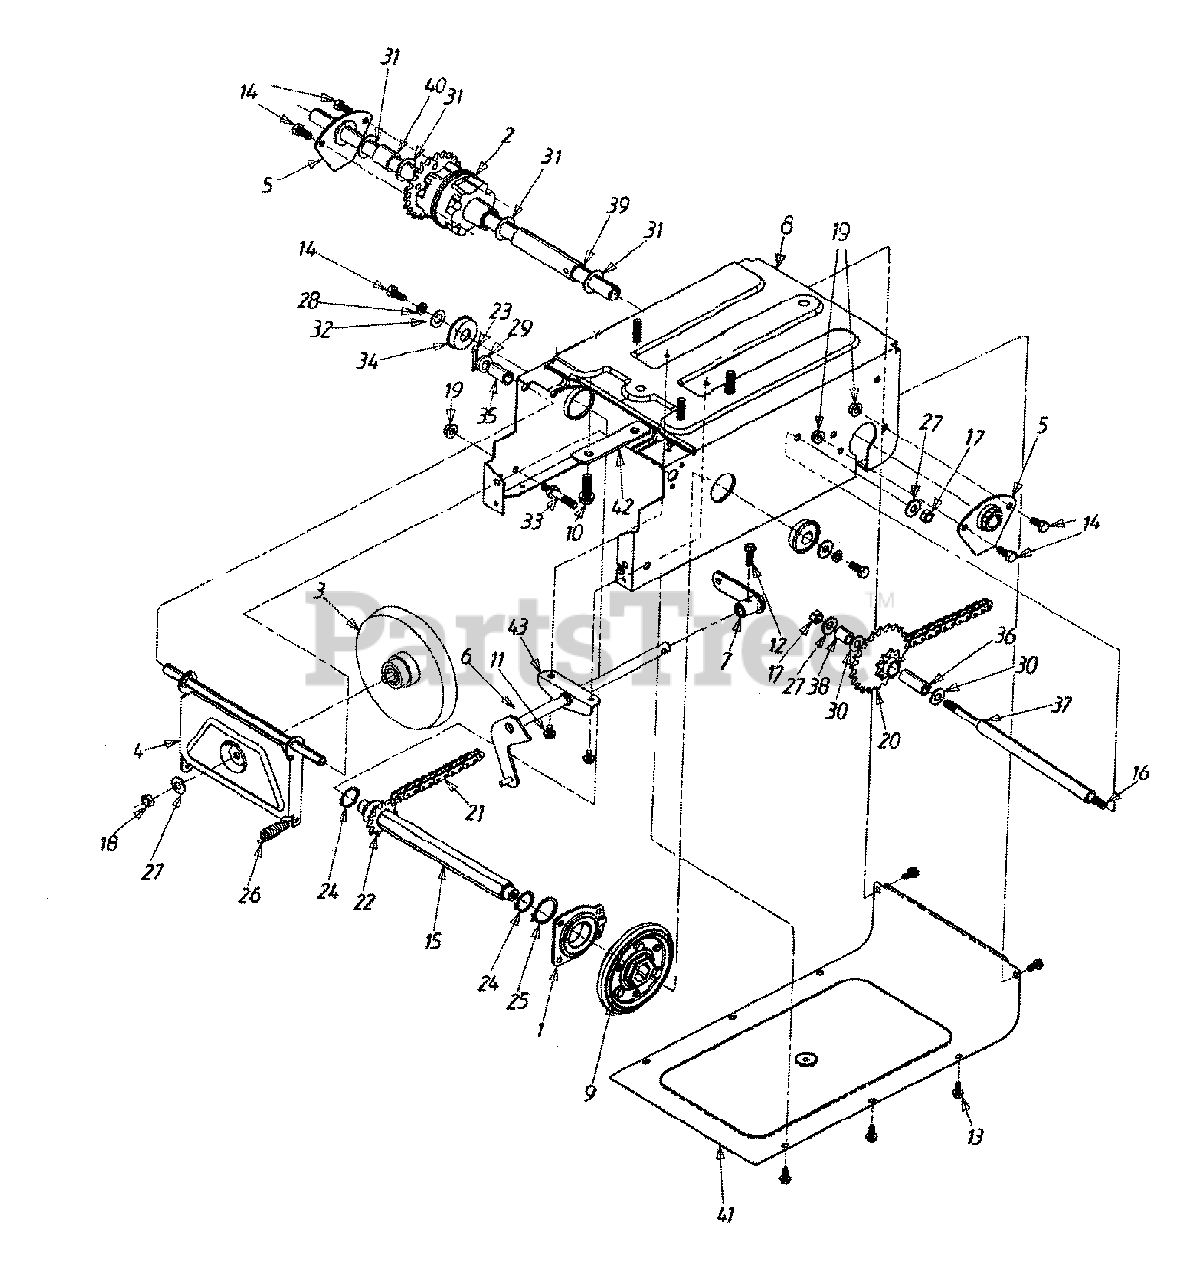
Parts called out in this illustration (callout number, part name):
1	BEARING ASSY-FRICTION WHEEL
2	DIFFERENTIAL ASSY COMP.
3	DISC-FRICTION WHEEL ASSY COMP.
3	DISC-FRICTION WHEEL
3	BOLT-SHOULDER
3	BEARING-BALL
4	BRACKET ASSY-SUPPORT
5	BRACKET ASSY-AXLE
6	SHAFT ASSY-SHIFT
9	WHEEL ASSY-FRICTION
10	SCREW-HEX SELF-TAP
11	SCREW-HEX WASHER
12	SCREW-HEX WASHER
13	SCREW-HEX
14	SCREW-HEX
15	SHAFT-HEX
16	SHAFT-JACK
17	NUT-HEX
18	NUT-HEX JAM
19	NUT-HEX FLANGE LOCK
20	SPROCKET & HUB
21	CHAIN
22	SPROCKET 11T
23	PIN-COTTER
24	RING-SNAP
25	RING-SNAP
26	SPRING-EXTENSION
27	WASHER-BELL
28	WASHER-LOCK
29	WASHER-FLAT
30	WASHER-FLAT
31	WASHER-FLAT
32	WASHER-FLAT
33	BOLT-IDLER
34	BEARING-BALL
35	SPACER
36	SLEEVE
37	SPACER
38	SPACER
39	SPACER
40	SPACER
